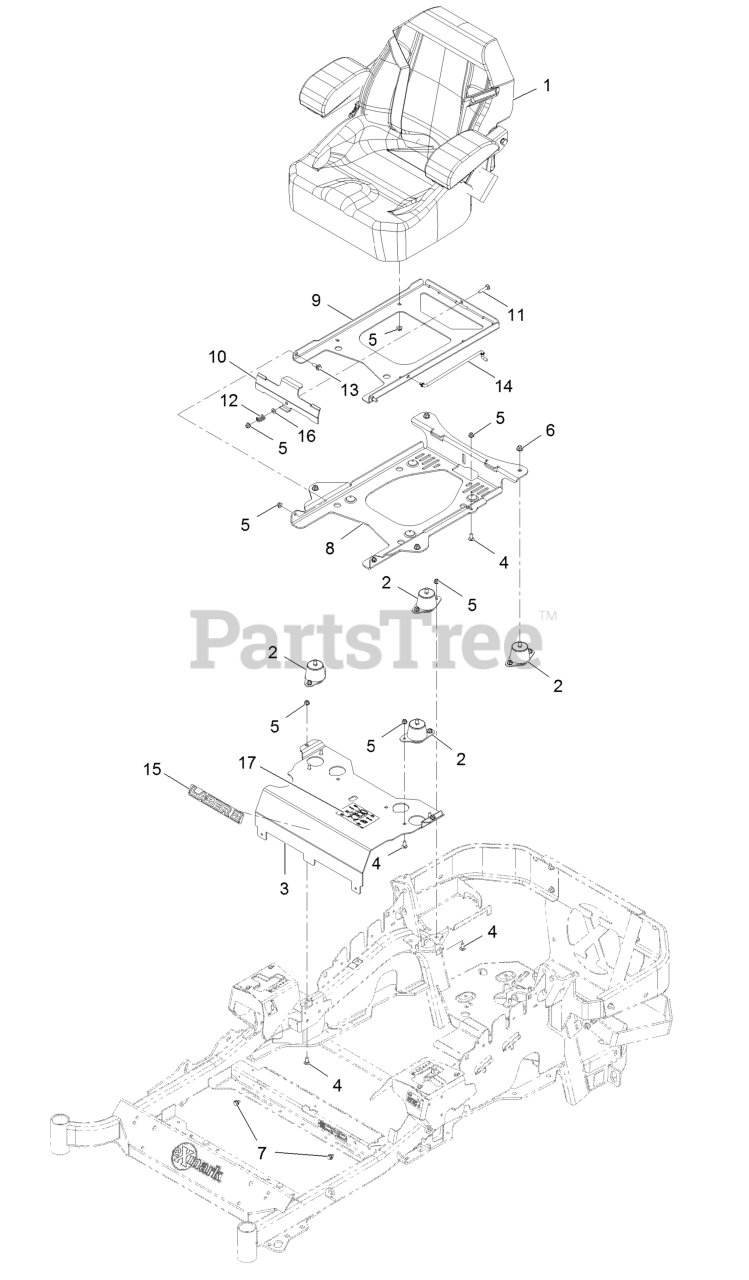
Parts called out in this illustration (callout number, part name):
1	Seat-Exmark Standard
2	Isolator-Seat
3	Panel-Front, Seat Mount
4	Bolt-Carriage 5/16-18 X 3/4 Short Neck
5	Nut-Nyloc 5/16-18 Flg
6	Nut-Nyloc 3/8-16 Flg
7	Screw-HWH 5/16 X 1/2 Tf
8	Plate-Tilt, Seat Support
9	Plate-Frame, Seat
10	Plate-Latch, Seat
11	Bolt-Carriage 5/16-18 X 1 1/2
12	Spring-Compression
13	Screw-Shoulder
14	Rod-Prop
15	Decal, Lazer Model
16	Washer-5/16 SAE
17	Decal-Service Aid
